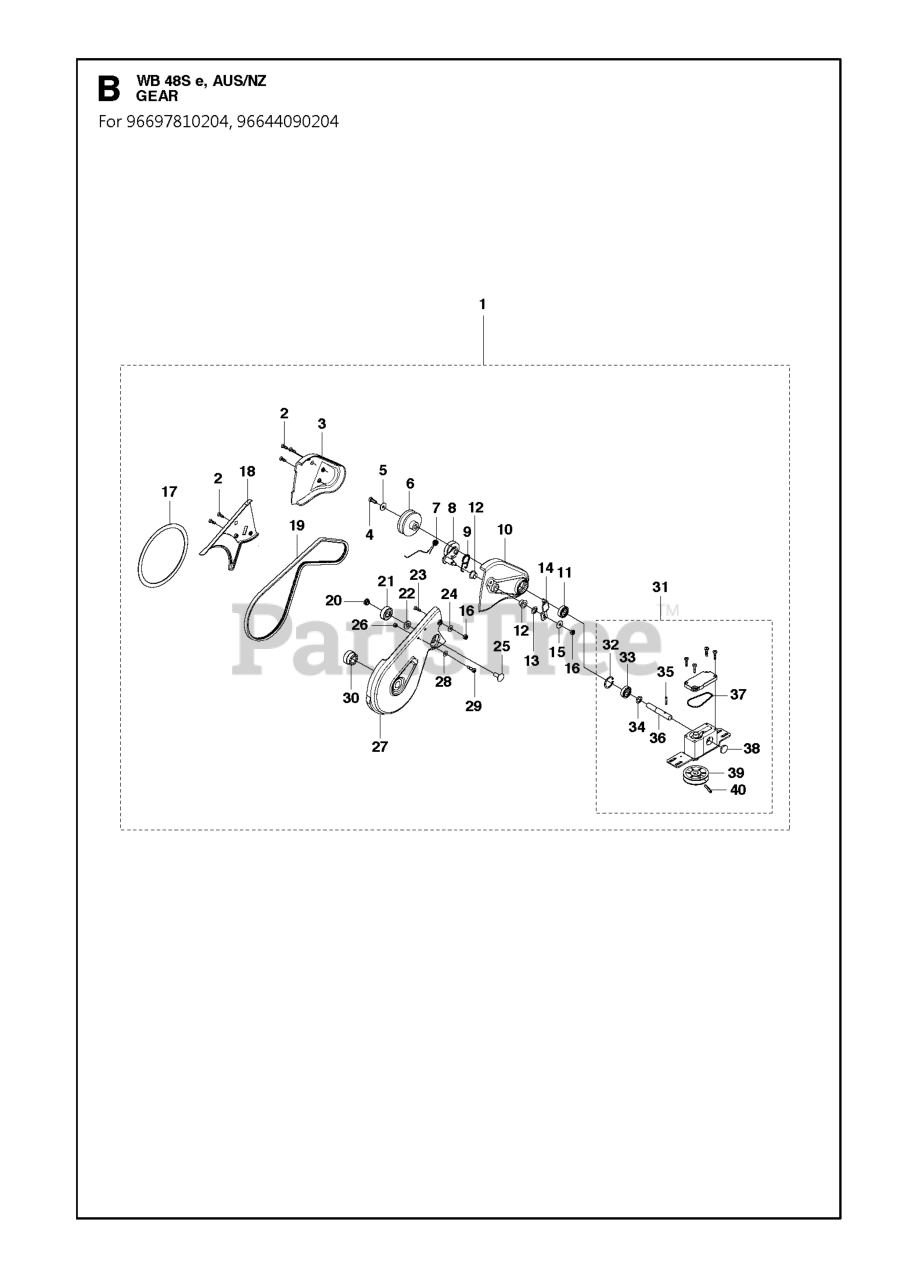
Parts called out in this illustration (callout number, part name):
15	WASHER 19X6X1
16	NUT FLANGE - M6
21	BALL BEARING 6201-2RS1
33	BALL BEARING
